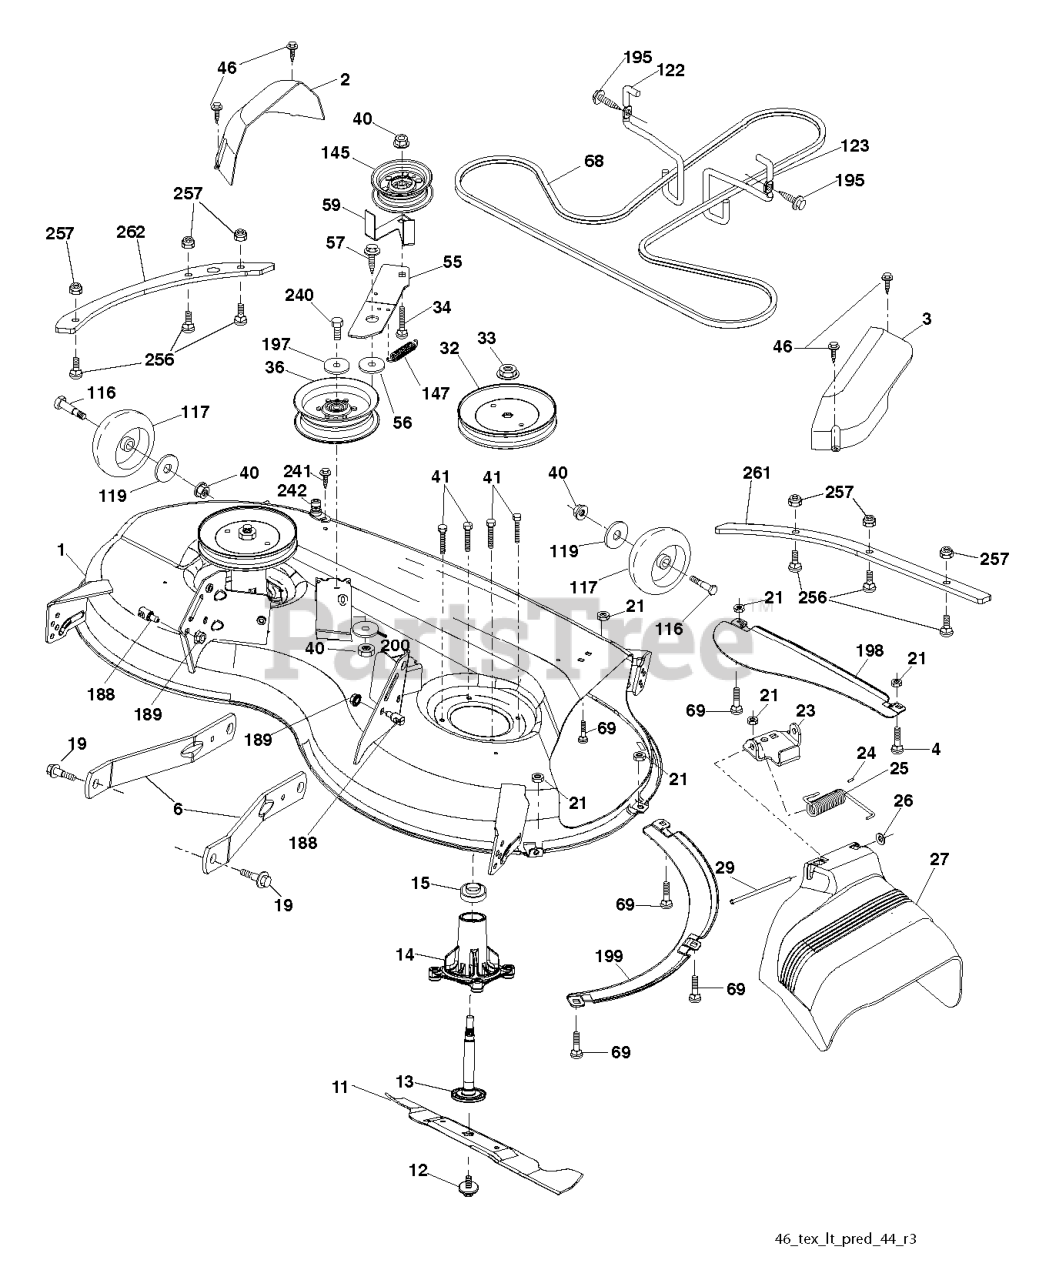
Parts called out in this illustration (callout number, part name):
1	DECK SVC 46"
2	COVER.MANDREL.RH.46"
3	COVER.MANDREL.LH.46"
4	BOLT
6	ARM.SUSPENSION.MOWER.R
8	BOLT.WASHER.ASM.7/16-2
11	BLADE.MOWER.46".HI.LIFT
13	SHAFT.ASM.MDRL.N/GREASE.38
14	RP.HOUSING.MANDREL.4PT.
19	BOLT.SHOULDER
21	LOCKNUT
23	BRKT.DEFLECTOR.38"2005+
24	CAP-SLEEVE LT
25	SPRING.TORSION.DEFLECT
26	NUT PUSH M
27	SHIELD.DEFLECTOR.MOWER.46"BLAC
29	ROD.HINGE
30	SCREW, WASHER HEAD
31	WASHER.SPACER.MANDREL
32	PULLEY.MANDREL.5.438.PD
33	NUT.FLANGE.LOCK.TOP
34	BOLT.3/8-16X1.50
36	PULLEY.IDLER.2006
40	NUT LOCK FLG 3/8-16 UNC
46	SCREW.1/4-20X5/8
55	IDLER.ARM
56	SPACER.RETAINER
57	SCREW 3/8-16X1
59	GUARD, BELT
68	V-BELT
69	BOLT
116	BOLT.SHOULDER.3/8-16X3-5/8.
117	RP WHEEL. GUAGE RALLY
119	WASHER
122	KEEPER BELT ENGINE LH
123	KEEPER BELT RH
145	PULLEY.IDLER.48"PRIMARY
147	SPRING.MOWER.DRIVE.ELECTRIC
188	STUD.FASTNER.W/ANTI-ROTATE
189	NUT LOCK HEX FLANGE 5/16-18
195	SCREW, 3/8-16X3/4
197	WASHER
198	BAFFLE CENTER FRONT
199	BAFFLE FRONT RH
200	WASHER.13/32 X 1 X 1/2.11GUARD
240	BOLT-HEX EAK
241	SCREW.TT.#10-32X.5.3/8.FLANGE
242	PORT.WASHOUT
256	SCREW.BUTTONHEAD.1/4-20X1
257	NUT T
261	PLATE.REINFOR.46.SIDEBOLT.X431
262	PLATE.REINFOR.46.SIDEBOLT.X431
